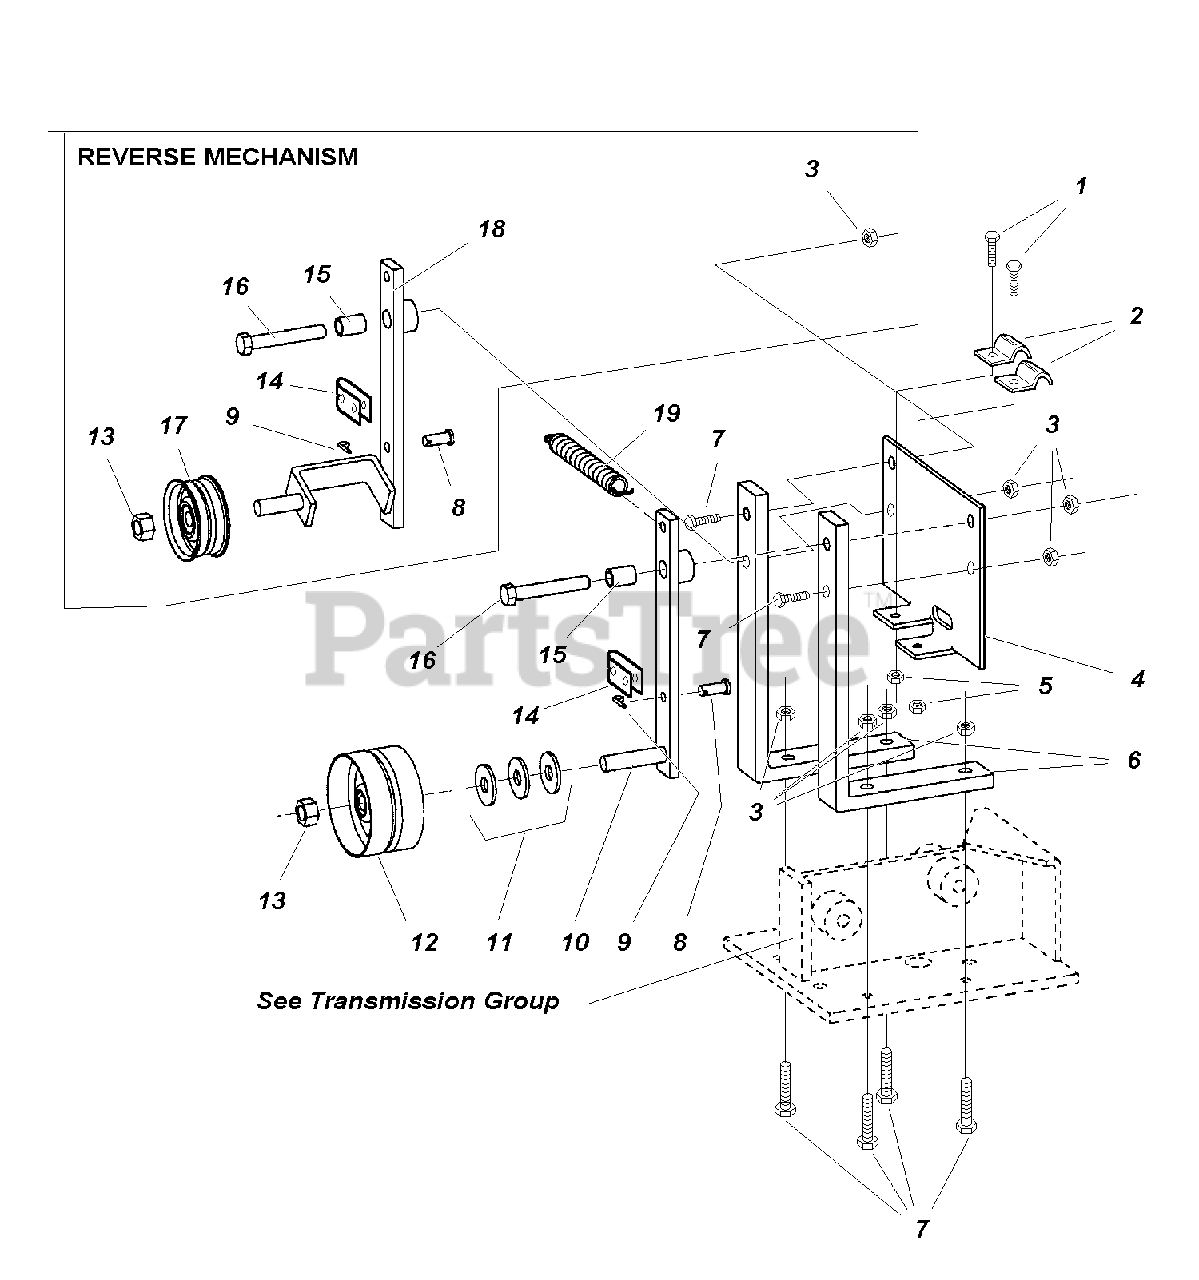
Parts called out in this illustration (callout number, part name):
1	CAPSCREW, 5MM x .8 x 16MM RT
3	NUT, Hex Flagne 5/16"- 18 Two, Way Lock
4	BRACKET, Cable Mount
5	NUT, Hex Nylok
6	BAR, Shift Mounting
7	CAPSCREW, 5/16"- 18 x 1-1/4" G5
8	PIN, Link Forward/Reverse
9	PIN, Cotter
10	ARM, Forward Idler
11	WASHER, 3/8"
12	PULLEY, Forward Idler
13	NUT, HEX 3/8"- 16
14	YOKE, Cable
15	BUSHING, Pivot, 5/16"
16	CAPSCREW, Hex Head 5/16-18 x 2 G5
17	PULLEY, Reverse
18	ARM, Idler Reverse
19	SPRING, Idler Arm
